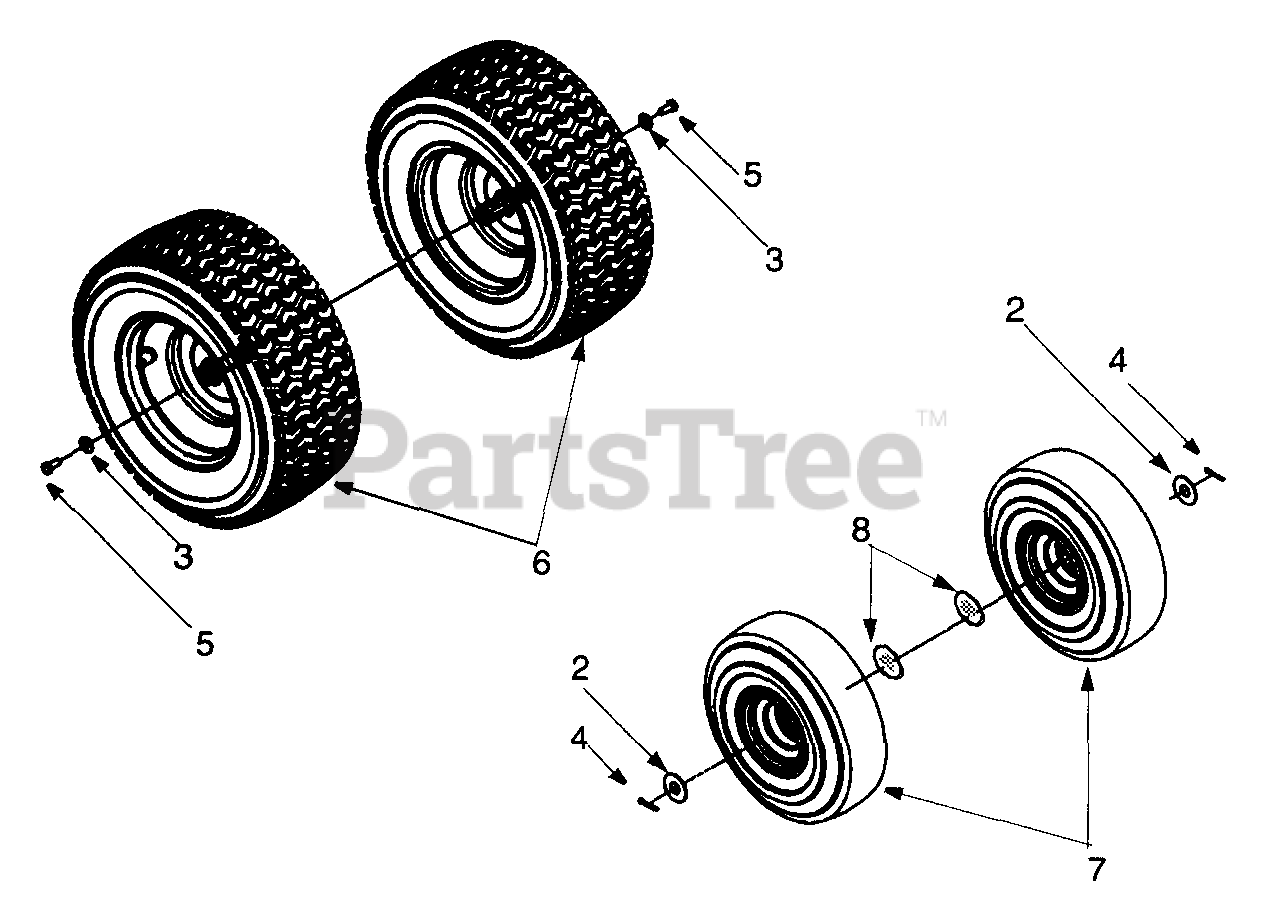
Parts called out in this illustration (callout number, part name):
2	Flat Washer .635 x 1.589 x .06
3	Bell Washer .345 I.D. x.88 O.D.x 06
4	Hairpin Clip
5	Hex Screw 5/16-24 x .75
